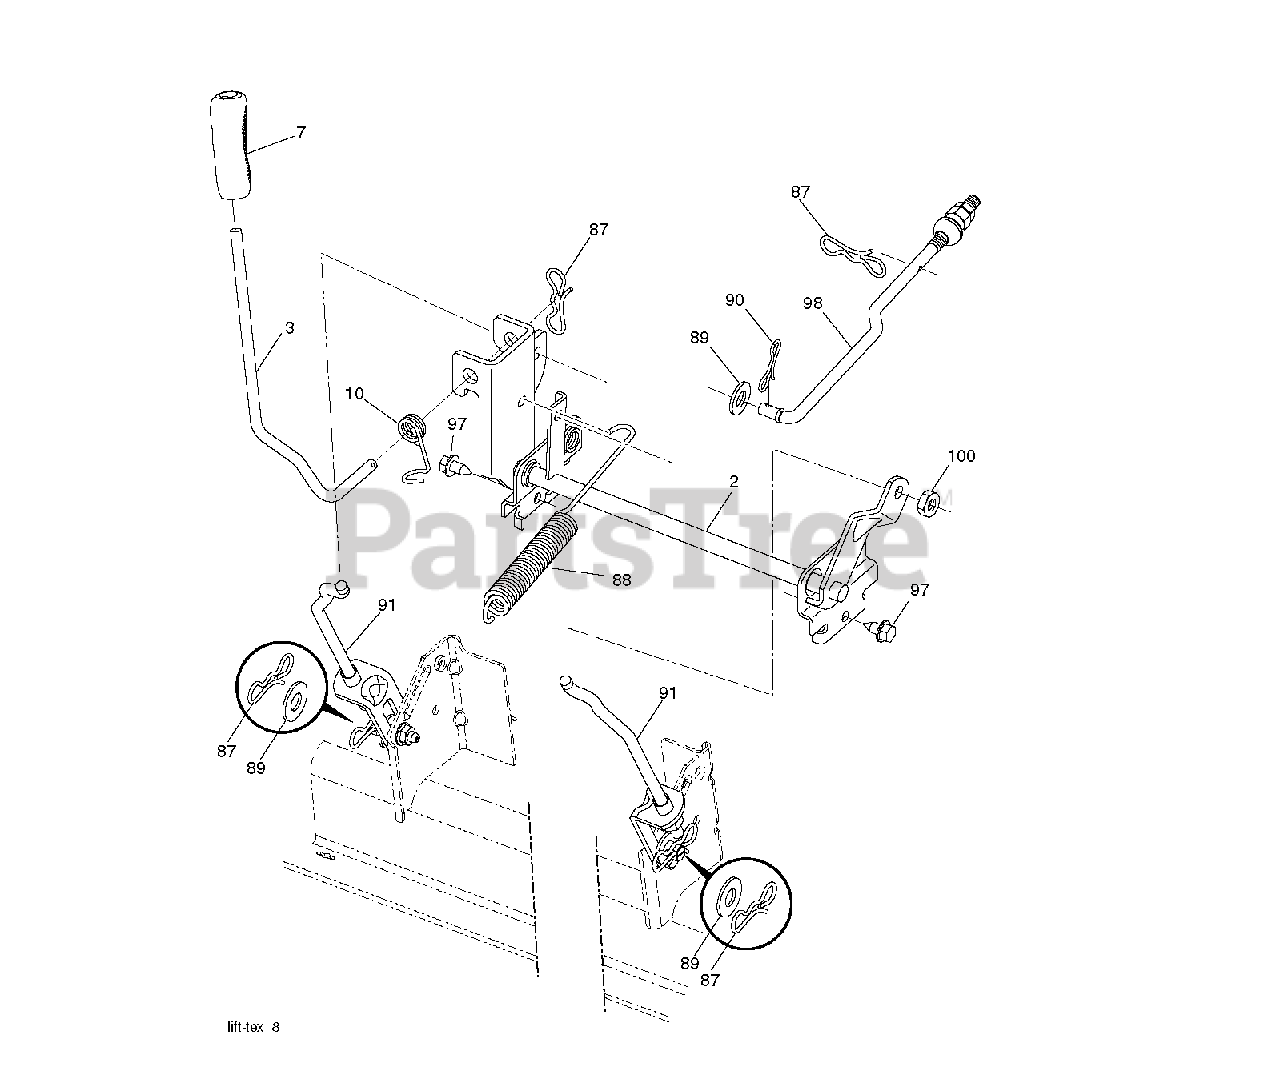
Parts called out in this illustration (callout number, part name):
2	SHAFT.ASM.LIFT.CROSS.H
3	LEVER.LIFT.HANDLE.LT
7	GRIP.LEVER.
10	SPRING.TORSION.LIFT.HANDLE
87	PIN.COTTER.7/16.BOW TI.
88	SPRING.LIFT.ASSIST
90	PIN.COTTER.5/16.BOW TI
91	LINK.ASM.LIFT.REAR
97	SCREW, 3/8-16X3/4
98	LINK.ASM.SUSP.FRONT.MW
100	LOCKNUT
